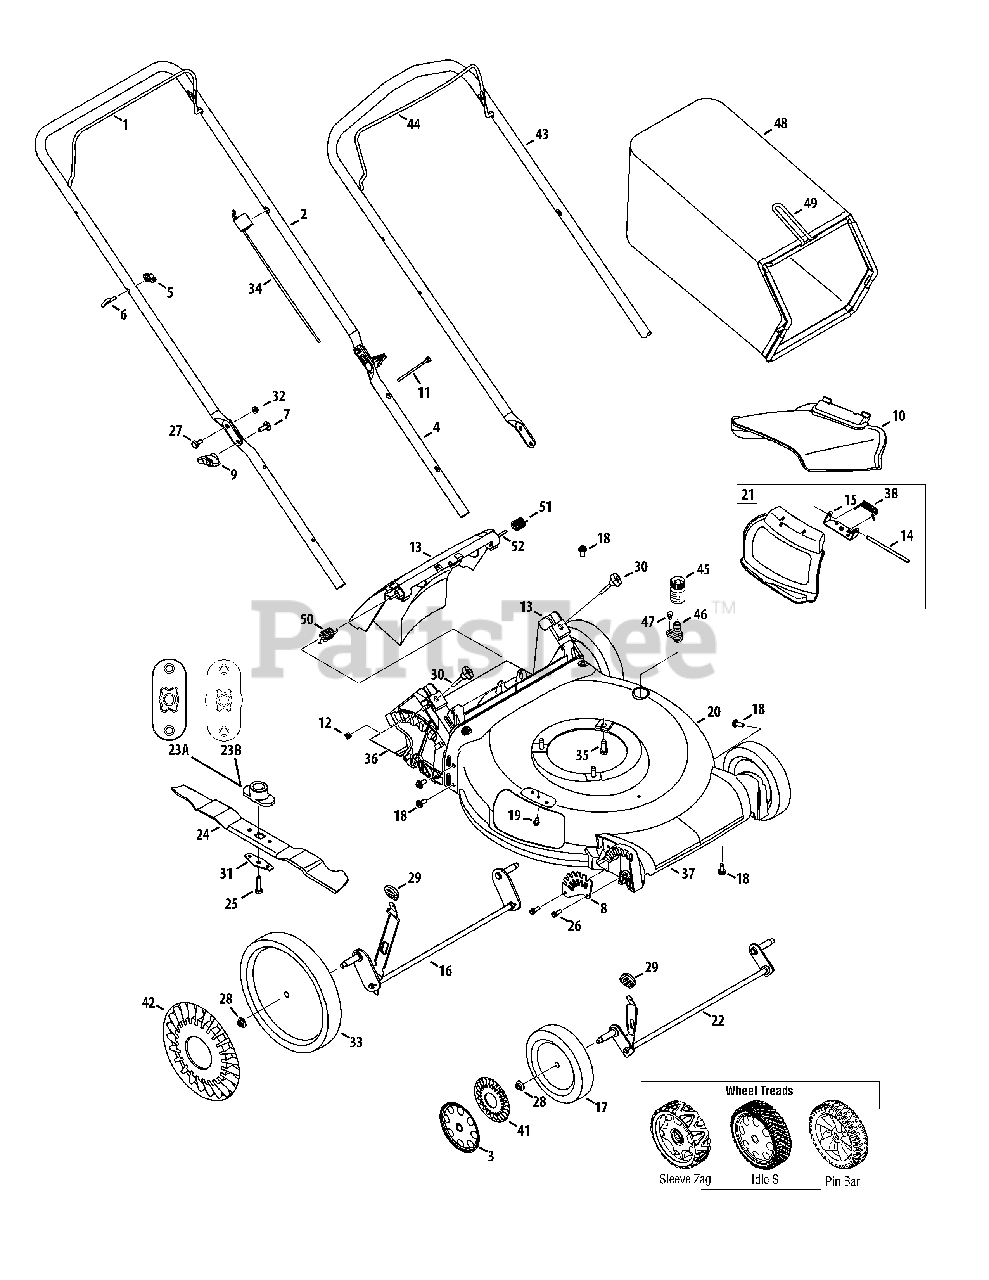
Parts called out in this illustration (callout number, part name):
1	Blade Control Handle - Black
2	Upper Handle - Black (adjustable)
3	Hub Cap
4	Lower Handle
5	Knob 1/4-20
6	Rope Guide Bolt
7	Carriage Bolt 5/16-18
8	Front Height Adjustment Plate
9	Wing Knob 5/16-18 Black
10	Chute Deflector
11	Cable Tiet
12	Sq. Nut 1/4-20
13	Rear Baffle
14	Hinge Pin
15	Chute Deflector Bracket
16	Rear Axle Ass'y - 8" wheel
17	Wheel Ass'y 7 x 2.0 Sleeve Zag Black
18	Hex Hd. Cap Screw 5/16-14 x .75
19	Sems TT Screw 1/4-20 x .50
20	21" Deck Ass’y (3 in 1 w/wash out Nozzle)
21	Hinged Mulch Plug Ass'y (Incl. ref. no.15, 38 & 14)
22	Front Axle Ass'y - 7 " wheel
23B	Blade Adapter (25 mm x 1.19)
24	21" Mulching Blade
25	Hex Bolt 3/8-24 x 1.5" Lg. (Gr 8)
26	Screw, 1/4-15 x .750
27	Shoulder Screw .375 x .126 x 1/4-20
28	Flange Locknut 3/8-16 Gr. F Nylon
29	Knob (Black)
30	Knob 1/4-20 x 1.725 Black
31	Blade Bell Support
32	Flanged Lock Nut 1/4-20 Gr. F Nylon
33	Rear Wheel Ass'y Zag Black
34	Control Cable, 160 cc Honda
35	Hex Wash HD Tap Scr 3/8-16 x .88
36	Trailing Shield 4.54 x 17.37
37	Front Axle Cover
38	Torsion Spring
42	Hub Cap (11")
43	Upper Handle (Ergo)
44	Blade Control Handle
45	Water Nozzle Adapter
46	Deck Water Nozzle
47	Shoulder Screw 1/4-20 x .50
48	Grassbag, Black Dust Block ing
50	Torsion Spring RH
51	Torsion Spring LH
52	Pivot Rod
